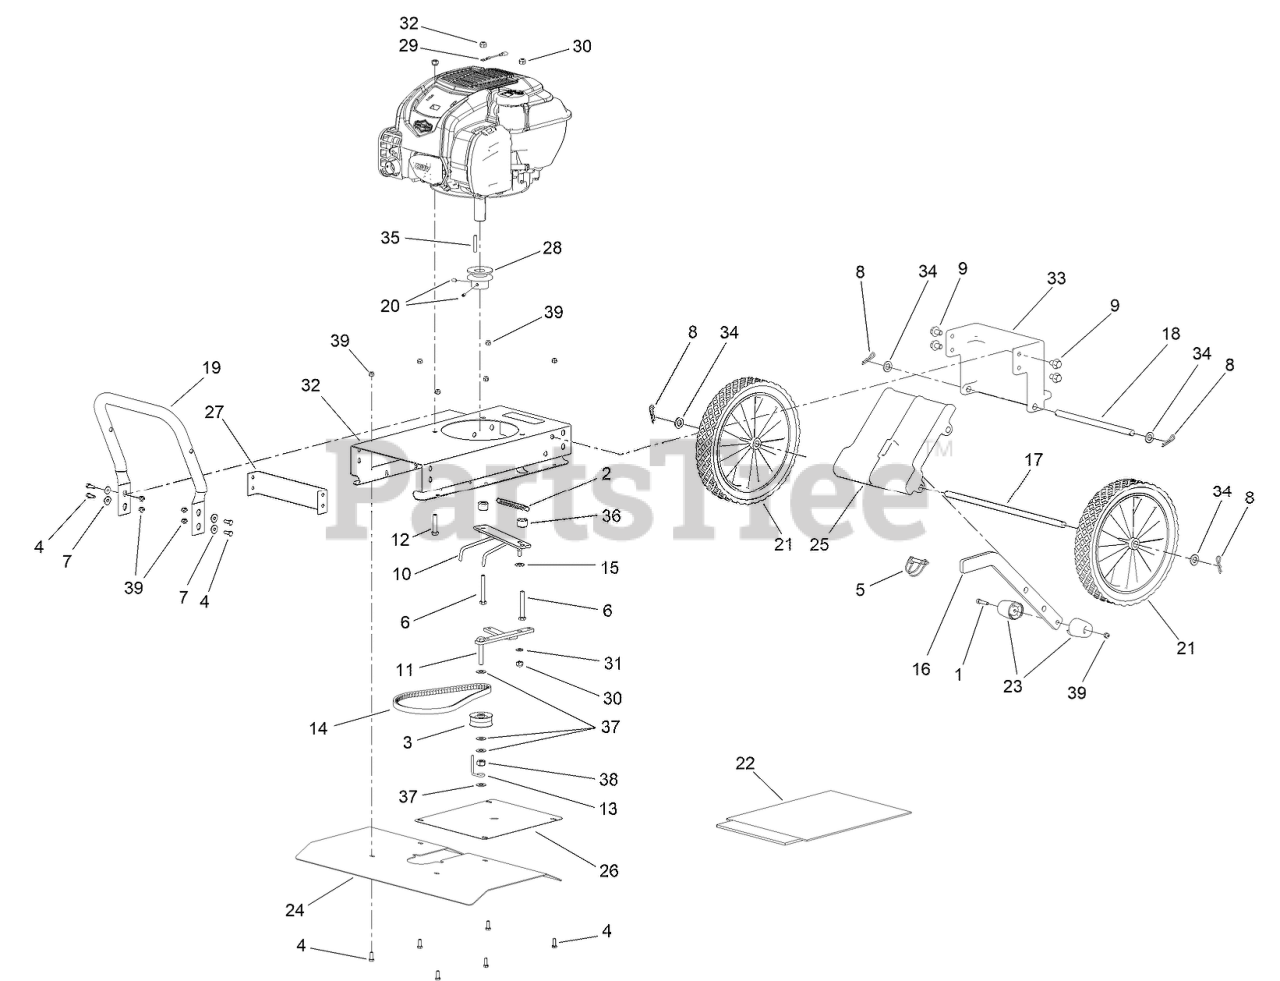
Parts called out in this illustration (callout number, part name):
1	SCREW-SHCS
2	SPRING-EXTENSION
3	PULLEY-IDLER
4	SCREW-HHCS
5	PIN-CLEVIS, LOCKING
6	SCREW-HHCS
7	WASHER-FLAT
8	PIN-COTTER
9	SCREW-HHSF
10	GUIDE-BELT
11	ARM-FORWARD
12	SCREW-HH
13	BELT CATCH
15	WASHER-PLAIN
16	STAKE-DRAG
17	SHAFT-WHEEL
18	SHAFT-PIVOT
19	HANDLEBAR-FRONT
20	SCREW-SET
21	WHEEL-GREY
22	BAG-MANUAL
23	HANDLE
24	SHIELD-TINE
25	TAIL MOUNT-LOWER
26	SHIELD-REAR
27	COVER-FRONT
28	PULLEY-ENGINE
29	WIRE-GROUND
30	NUT-HEX
31	WASHER-FLAT
32	FRAME-RED
33	TAIL MOUNT-UPPER
34	WASHER-WHEEL
35	KEY-SQUARE
36	SPACER-ARM
37	WASHER-PLAIN
38	NUT-HEX
39	NUT-HEX
